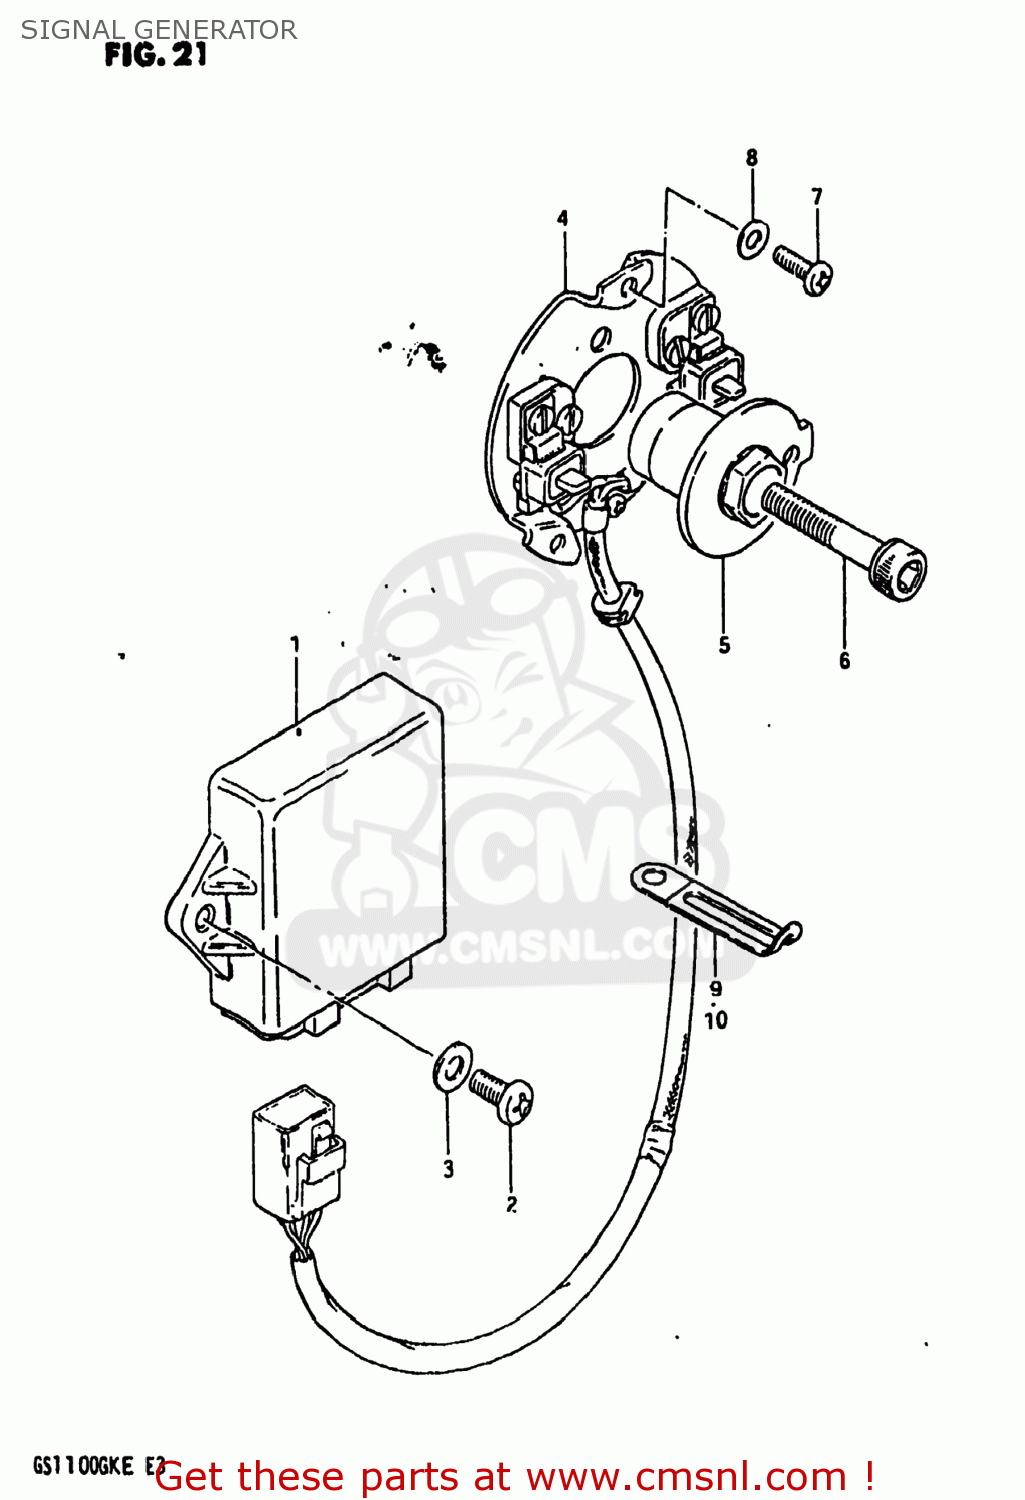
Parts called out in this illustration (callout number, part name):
1	IGNITOR UNIT,ESA
2	SCREW 6X12
3	WASHER
4	STATOR,SIGNAL GENERATOR
5	ROTOR,SIGNAL
6	BOLT
7	SCREW(5X12)
8	WASHER(5.5X10X0.8)
9	CLAMP L:35
10	CLAMP
